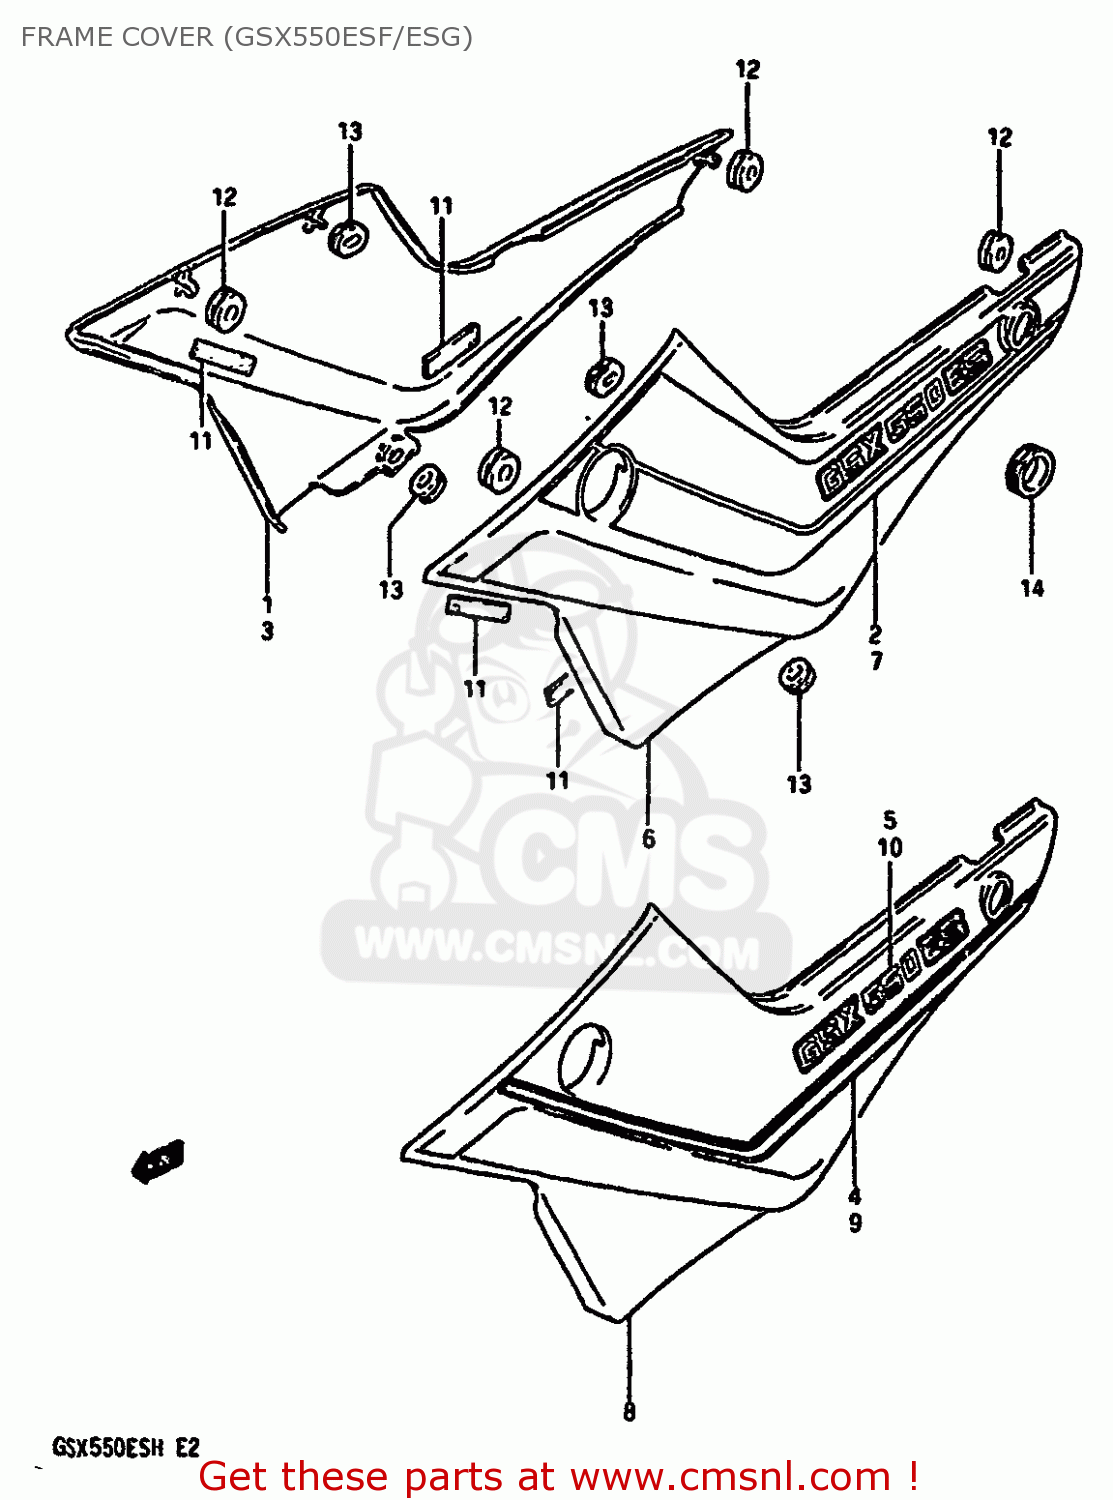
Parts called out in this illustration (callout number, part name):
1	COVER,FRAME RH (WHITE)
2	TAPE SET,FRAME COVER RH
3	COVER,FRAME RH
4	TAPE SET,FRAME COVER RH
5	EMBLEM
6	COVER,FRAME LH
7	TAPE SET,FRAME COVER LH
8	COVER,FRAME LH
9	TAPE SET,FRAME COVER,LEFT
10	EMBLEM
11	RUBBER,FRAME COVER
12	CUSHION
13	CUSHION
14	GROMMET,SEAT LOCK HOLE
